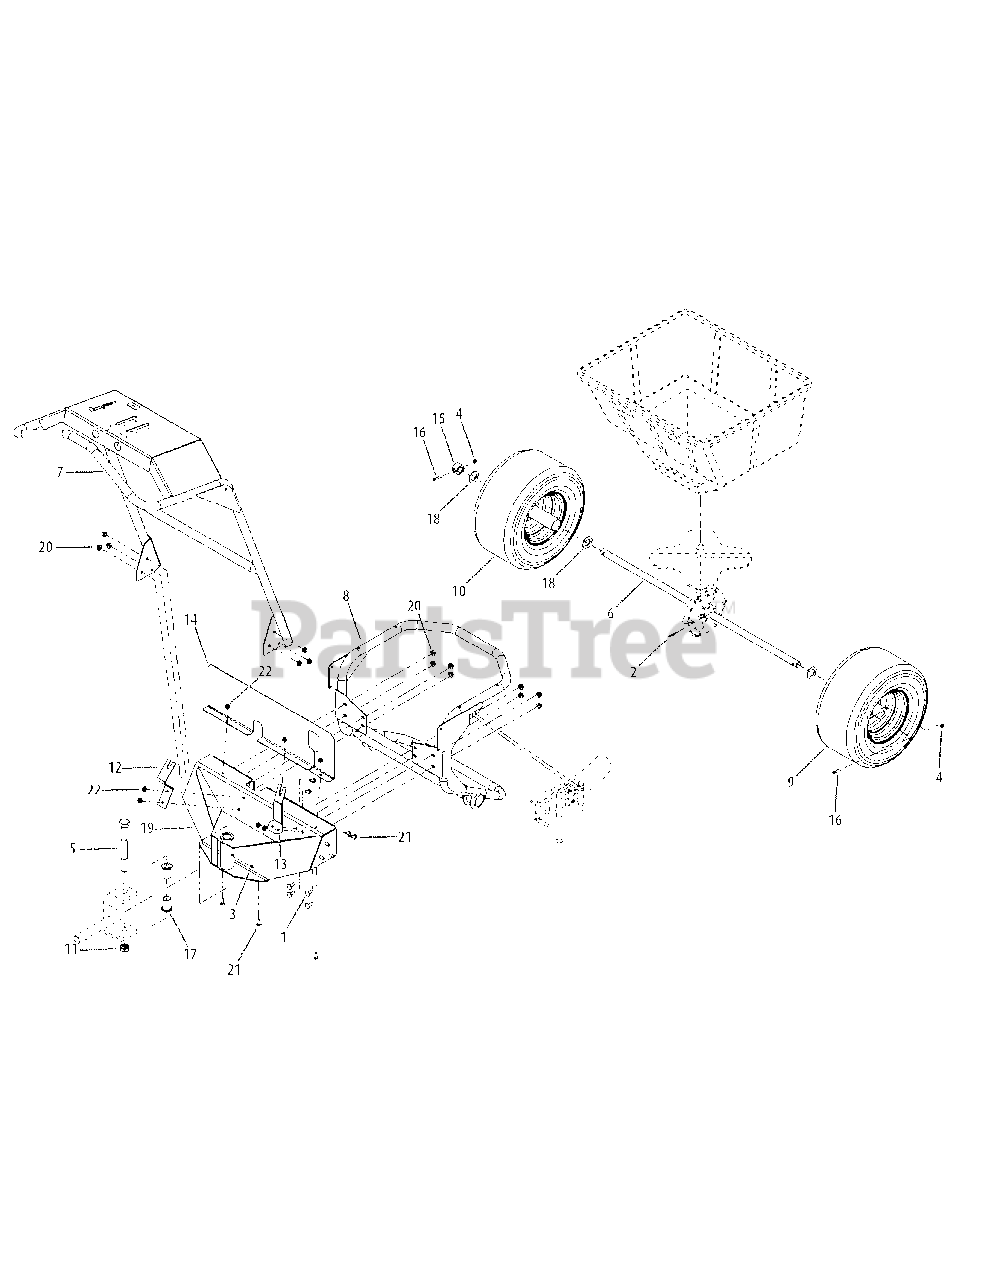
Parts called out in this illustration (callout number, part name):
1	Carriage Bolt, 5/16-18 x 3/4, SS
2	Roll Pin, 5/32 x 1-1/4, SS
3	Grease Fitting, 1/4-28 x 3/16
4	Nut, #10-24
5	Hex Cap Screw, 3/4-16 x 6.50
6	Front Axle
7	Handle Weldment
8	Front Frame bearing Assembly Includes:
8	Grease Fitting, 1/4-28 x 3/16
8	Axle Bearing
9	Drive Wheel Assmebly, 13 x 6.5-6
10	Idler Wheel Assembly, 13 x 6.5-6
11	Jam Nut, 3/4-16
12	Shut-Off Cable bracket
13	Deflector Cable bracket
14	Shield, SS
15	Shaft Collar
16	Screw, 10-24 x 1.25
18	Washer, .89ID x 1.5OD x .09, SS
19	Pivot Bracket Weldment
20	Nut, 5/16-18, Flange Whiz, SS
21	Carriage Bolt, 1/4-20 x 3/4, SS
22	Nut, 1/4-20 Flange Whiz, SS
